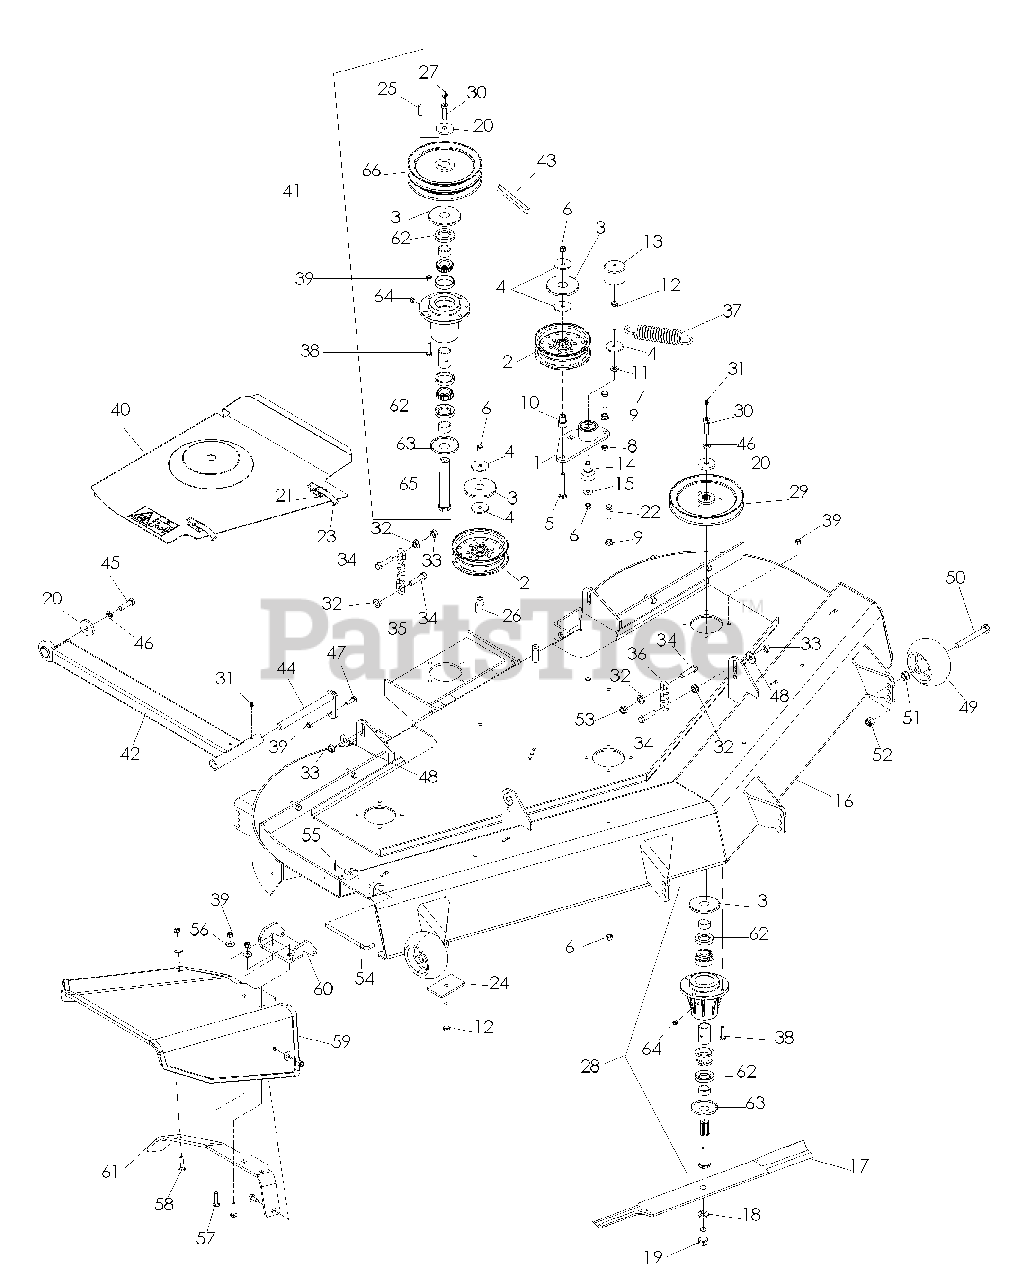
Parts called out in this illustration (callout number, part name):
1	ARM, IDLER W/BEARINGS
2	IDLER PULLEY
3	TOP DUST CAP
4	WASHER 3/8 SPECIAL
5	RHSNB 3/8-16 x 2 3/4
6	NUT 3/8-16 HEX NYLOC
7	HCS 3/8-16 x 1/2 GR8
8	NUT 3/8-16 HEX JAM
9	NUT 3/8-16 HEX WHIZLK
10	BUSHING, IDLER
11	WASHER 3/8 SAE FLT
12	HCS 3/8-16 x3
13	CAP, VINYL
14	PIVOT, BEARING
15	WASHER 3/8 FLAT STD
16	TUNNEL DECK W/DECALS
17	BLADE, 25"
18	WASHER 5/8 SLOTTED LOCK
19	HCS 5/8-18 x 1 1/4
20	WASHER, HEAVY
22	HCS 3/8-16 x 1 1/4
23	DRAW LATCH
24	PAD
25	KEY 1/4 SQ x 1 1/8
26	IDLER BUSHING
27	ZERK 90° 1/4-28
28	HOUSING ASSEM
30	HCS 7/16-20 x 1 1/2 GR8
31	ZERK
32	NUT 7/16-14 HEX WHIZ LK
33	NUT 7/16-14 HEX NYLOC
34	HCS 7/16-14 x 1 3/4
35	LIFT CHAIN
36	LIFT CHAIN, 3 LINK
38	HCS 5/16-18 x 1 1/4
39	NUT 5/16-18 HEX NYLOC
40	BELT SHIELD ASSEM RH
40	BELT SHIELD ASSEM LH
41	JACKSHAFT ASSEM LOWER
43	BELT
45	HCS 7/16-20 x 1 1/2
46	WASHER 7/16 SPLT LOCK
47	HCS 5/16-18 x 1
48	WASHER 7/16 FLAT
49	WHEEL, GAUGE
50	HHB 1/2-13 x 4
51	NUT 1/2-13 HEX
52	NUT 1/2-13 HEX NYLOC
53	NUT 7/16-14 HEX CNTRLK
54	PIN, CHUTE PIVOT
55	PIN, COTTER 1/8 x 3/4
56	WASHER 5/16 STD FLT
57	RHSNB 5/16-18 x 1 1/2
58	RHSNB 5/16-18 x 1 1/4
59	DISCHARGE CHUTE
60	BRACKET, CHUTE
61	REINFORCMENT, BRACKET
62	SHAFT SEAL
63	BOTTOM DUST CAP
64	POPPET, GREASE
65	JACKSHAFT SPINDLE
